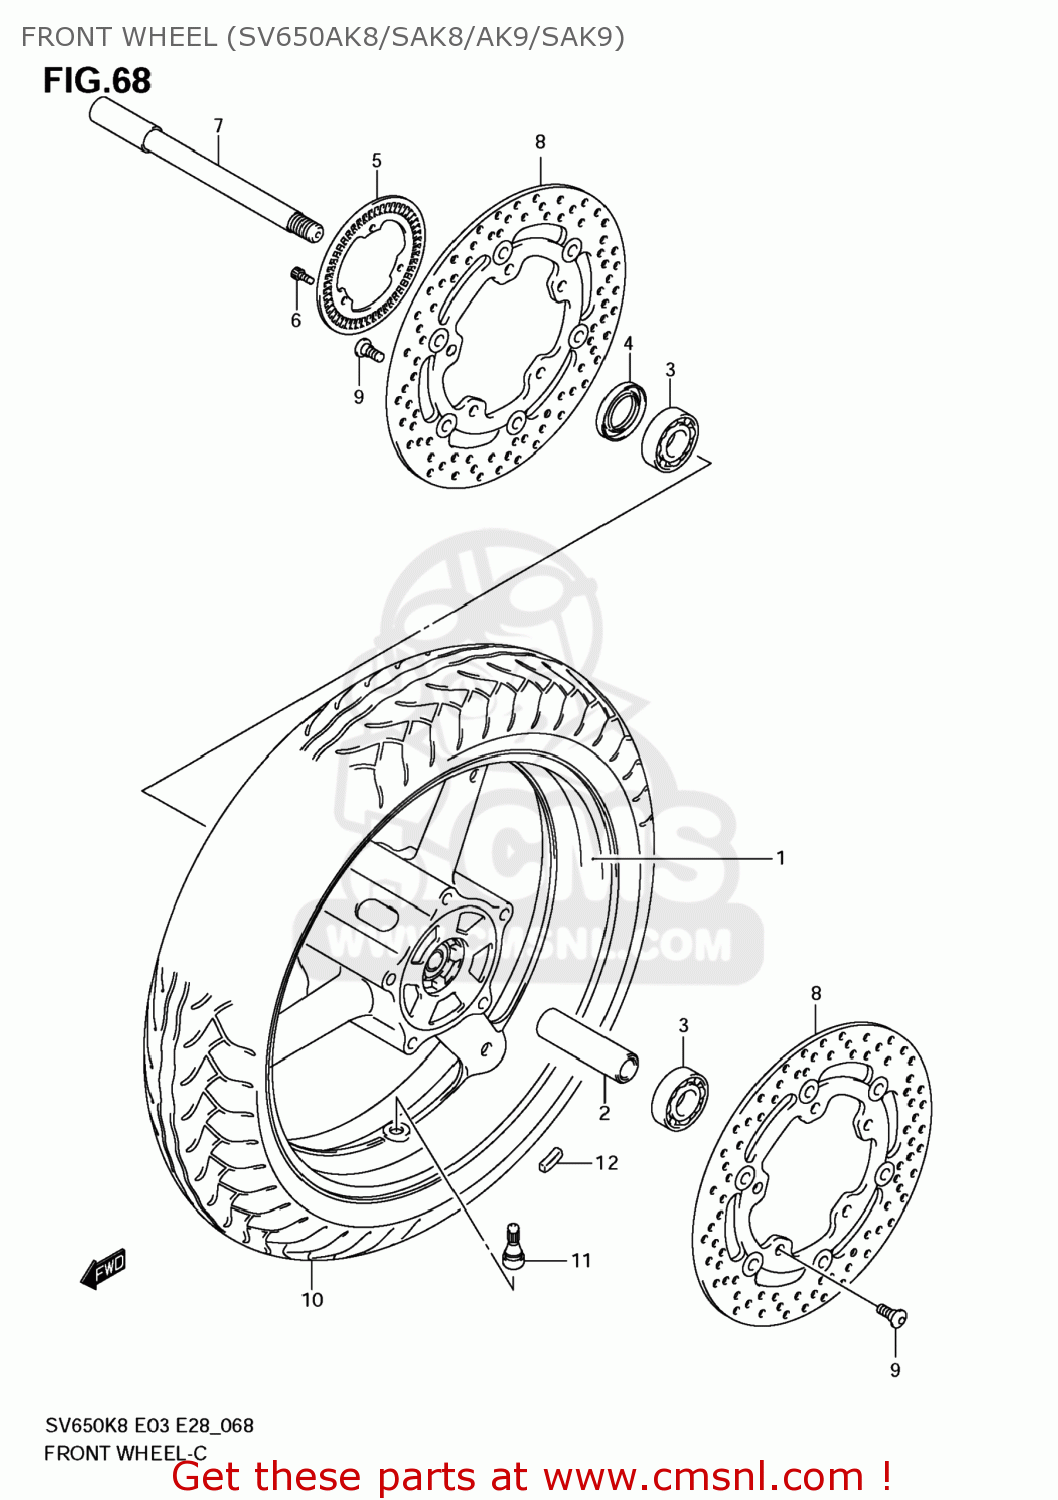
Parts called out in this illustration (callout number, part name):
1	WHEEL,FR(17M/CXMT3.50)
2	SPACER(17.5X25X88)
3	BEARING
4	SEAL,OIL(24X40X7)
5	RING,SPEED SENSOR FR(50T)
6	BOLT
7	AXLE,FR
8	DISC,FR BRAKE
9	BOLT(8X21)
10	TIRE,FR(120/60ZR17M/C 55W)
11	VALVE ASSY,WHEEL RIM(TR412)
12	BALANCER,WHEEL(10G)
